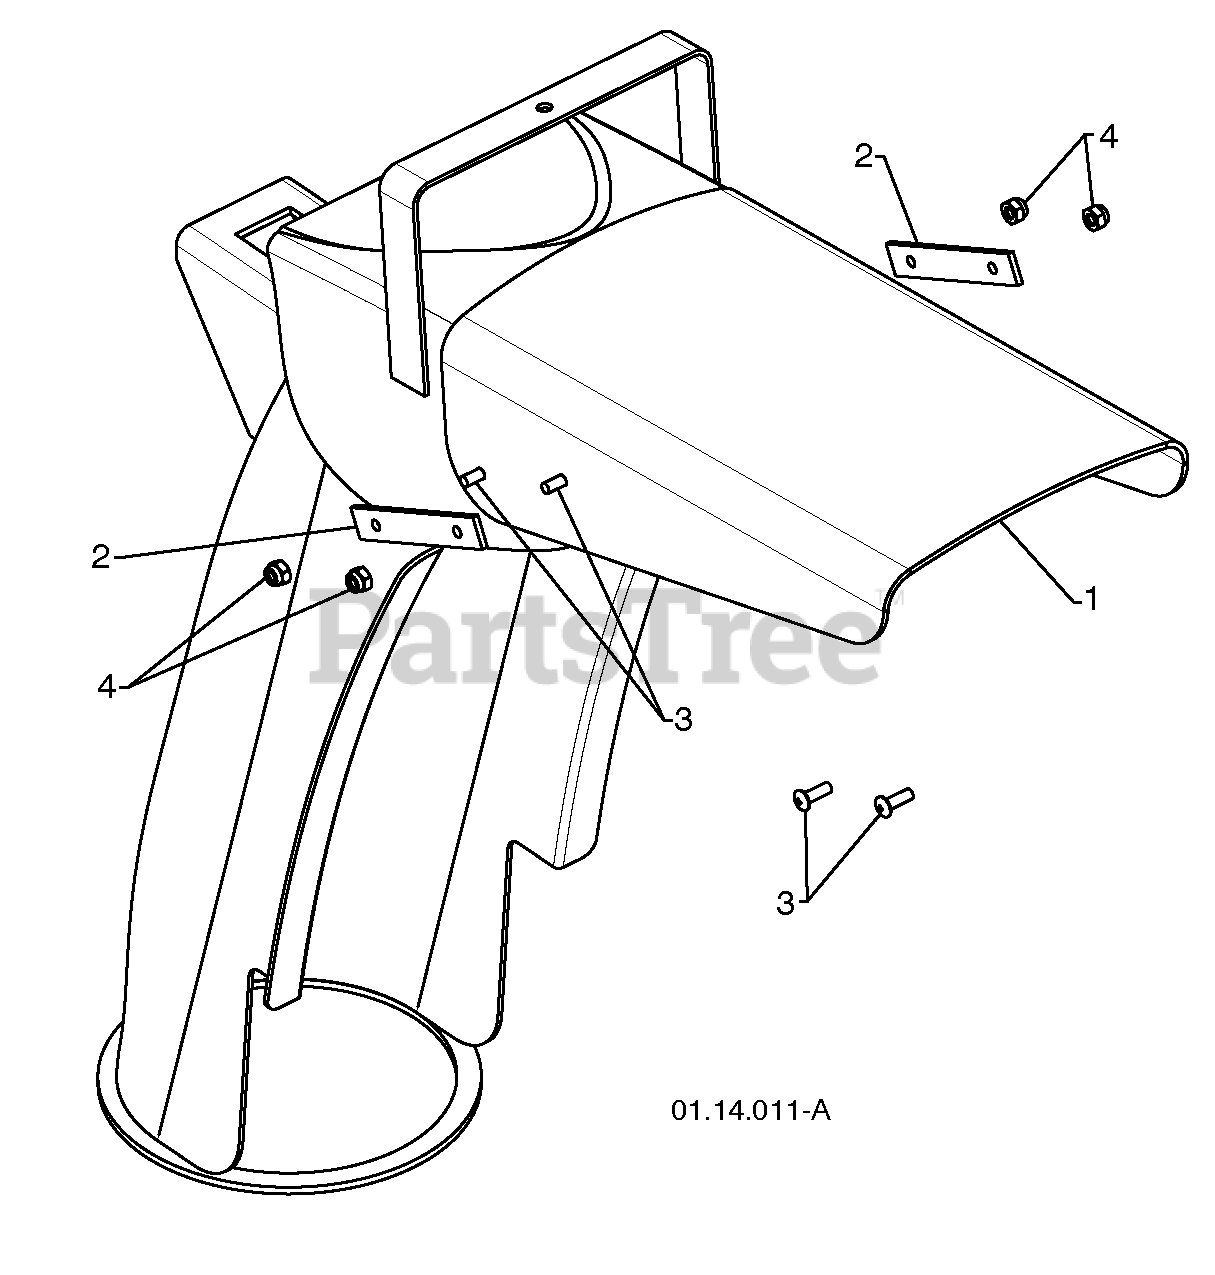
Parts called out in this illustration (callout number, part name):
1	SHIELD DEFLECTOR
2	STRAP
3	SCREW 8-32 X .50
